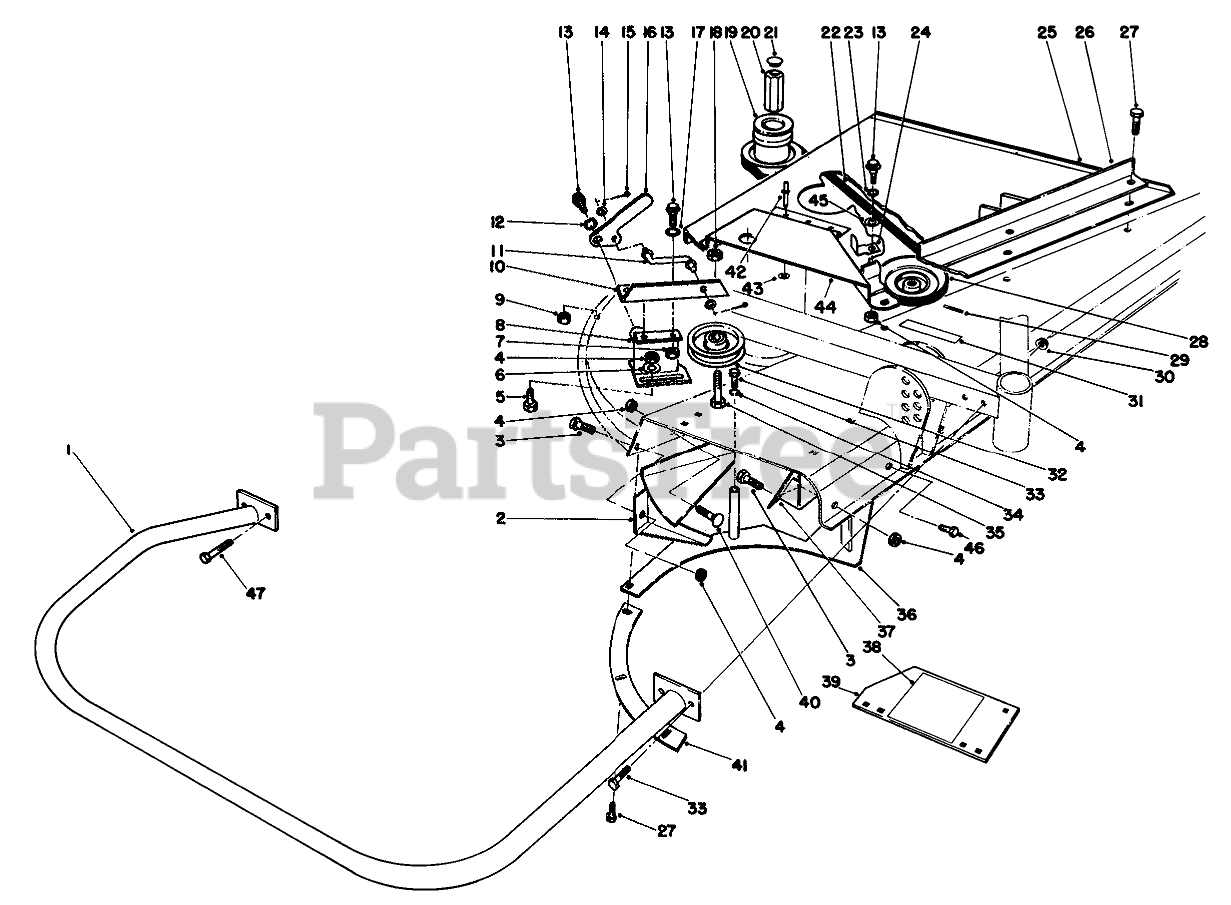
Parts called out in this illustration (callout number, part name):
1	Bumper
2	Deflector Rear
3	SCREW-HH
4	NUT-LOCK, CONE
5	SCREW-HH
6	WASHER-FLAT
7	NUT-LOCK, NI
8	Bracket-Idler
9	NUT-LOCK, CONE
10	Slide-Idler
11	Idler Rod
12	WASHER-SPRING
13	SCREW-SHOULDER
14	WASHER-PLAIN
15	PIN-COTTER
16	Lever-Idler
17	WASHER
18	NUT-LOCK, NI
19	Pulley (Splined)
20	NUT-PULLEY
21	NUT-COVER
22	V-BELT
23	WASHER-SPRING
24	Latch
25	RH COVER WA R
26	SPRING BRKT WA R
27	SCREW-HH
28	Pulley-Gear Box
29	PIN-ROLL, SLOTTED
30	NUT-FLANGE
31	WARNING DECAL
32	PULLEY-IDLER
33	SCREW-HH
34	WASHER-LOCK
35	SCREW-HH
36	Rear Shelf
37	Deflector-Front
38	Decal-Caution
39	Cover Plate Assembly (Incl. Ref. #38)
40	BOLT-CARR
41	Shelf-RH
43	WASHER-FLAT
44	PULLEY COVER WA R
45	WASHER-FLAT
46	SCREW-HH
47	SCREW-HH
